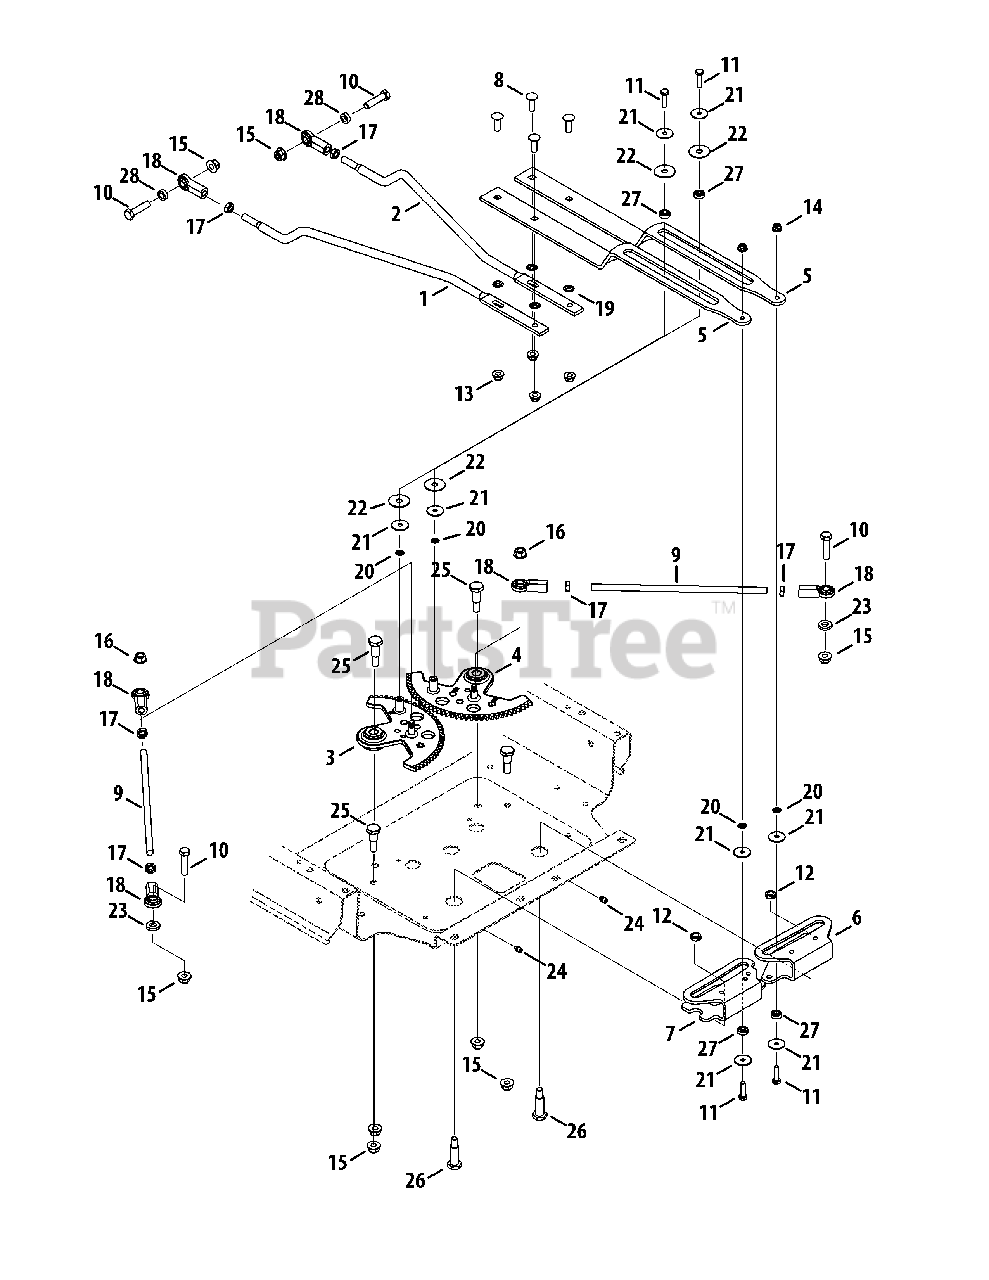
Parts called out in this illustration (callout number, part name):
1	Hydro Link, RH
2	Hydro Link, LH
3	Steering Gear Assembly, RH
4	Steering Gear Assembly, LH
5	Control Link
5	ZF-S STEERING KIT (REPL 703-08600)
6	Speed Cam Plate, LH
7	Speed Cam Plate, RH
8	Carriage Screw, 5/16-18 x 1.00
9	Drag Link, .375 Dia.
10	Hex Screw, 3/8-16 x 1.50
11	Hex Screw, 1/4-20 x 1.00
12	Nut, Jamlock, 3/8-16
13	Flange Lock Nut, 5/16-18
14	Flange Lock Nut, 1/4-20
15	Flange Lock Nut, 3/8-16
16	Nut, 5/16-18, Centerlock
17	Jam Nut, 3/8-24
18	Female Ball-Joint
19	Speed Nut, .3125 ID
20	Push Nut, .25 ID x .50 OD
21	Flat Washer, .285 x 1.25 x .060
22	Washer, .355 x 1.25 x .048
23	Flat Washer, .407 x .812 x .135
24	Grease Fitting, 3/16
25	SHOULDER SCREW .625 x .875 x 3/18
26	Shoulder Screw, .500 x 1.25 x 3/8-16
27	Ball Bearing, .25 x .625
28	Spacer, .380 ID x .625 OD x .21
